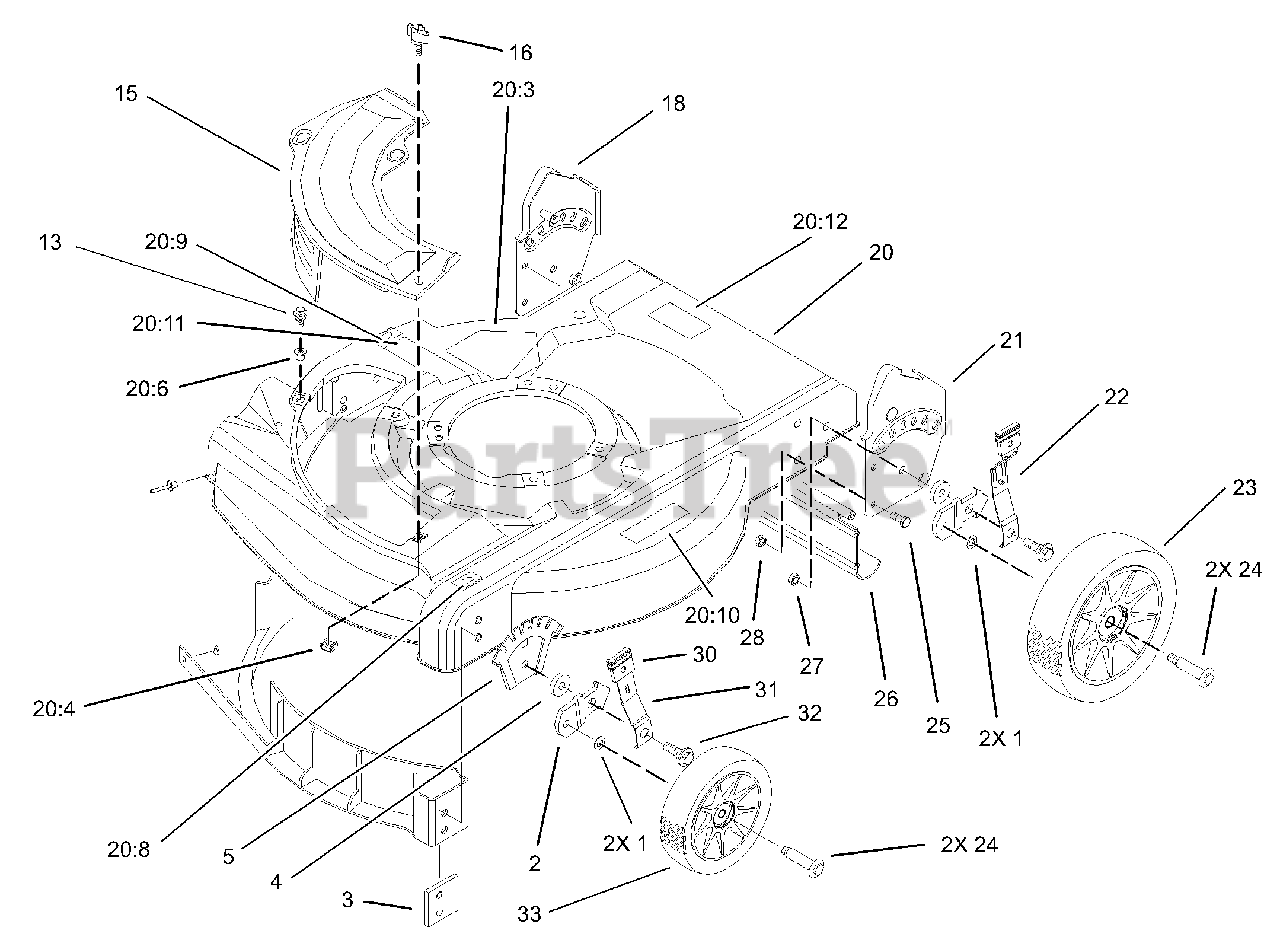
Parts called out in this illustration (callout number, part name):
2	Bracket-Height Adjustment, Wheel
3	Plate-Baffle
4	Washer-Wheel
5	Plate-Height, Adjustment
13	Screw-Sems
15	Plate-Mulch
18	RH Handle Brkt ASM
20:3	Danger Decal
20:4	Nut-Cage
20:6	Grommet-Plastic
20:8	Decal-HOC,LH
20:9	Decal-HOC,RH
20:10	Decal-Warning
20:11	Decal-Warning
20:12	Decal-Manual,Lb
21	LH Handle Brkt ASM
22	Rear Spring Arm ASM
23	Wheel & Tire 8"
24	Bolt-Shoulder
25	Screw-HH
26	Shield-Trailing
27	Nut-Lock, NI
28	Nut-Lock, NI
30	Knob-Lever, Height Adjustment
31	Arm-Front Spring
32	Bolt-Shoulder
33	Wheel & Tire 6"
